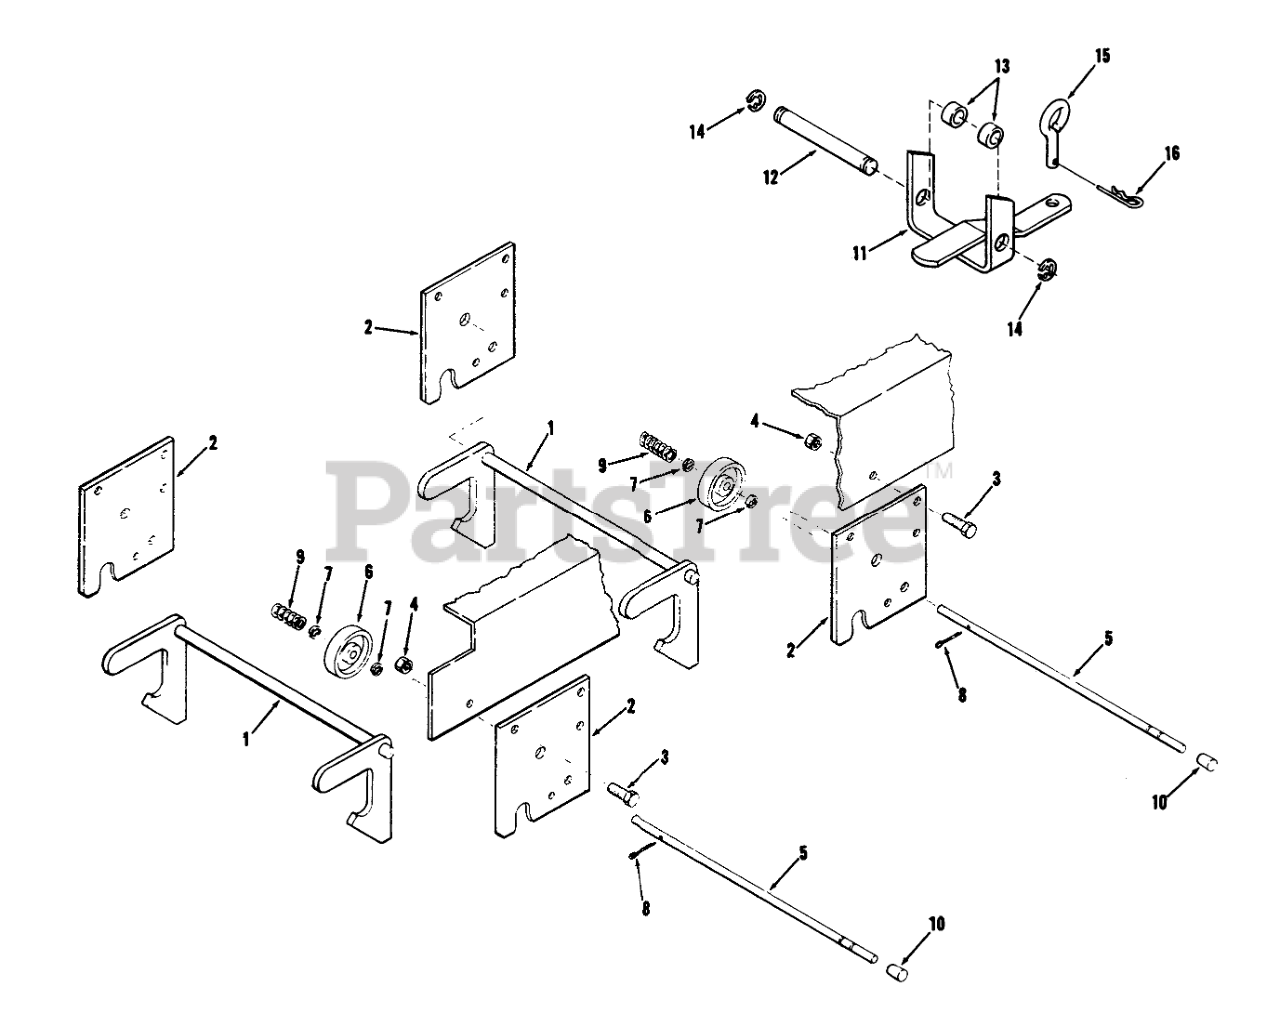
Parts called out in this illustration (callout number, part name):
1	Assy-Latch
2	Hitch Plate
3	BOLT
4	NUT
5	Rod Lock
7	RING-RETAINING
8	Cotter Pin
9	SPRING-COMPRESSION
10	CAP-ROD, PLUNGER
11	Hitch
12	PIN-STATIONARY HITCH
13	SPACER
14	E-RING
15	Pin-Tool
16	Hairpin
